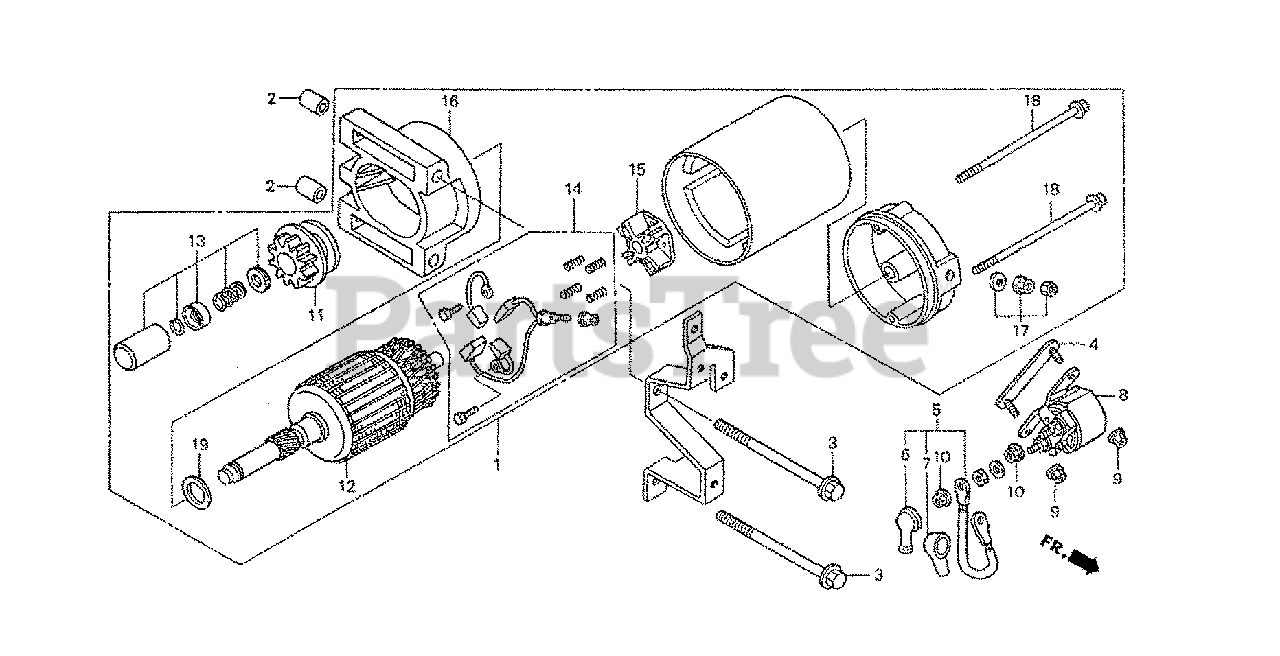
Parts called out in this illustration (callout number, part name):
1	MOTOR ASSY., STARTER
2	PIN, DOWEL (10X12)
3	BOLT, FLANGE (8X110)
11	GEAR SET, PINION
12	ARMATURE
13	STOPPER SET, PINION
14	BRUSH SET
15	HOLDER, BRUSH
16	BRACKET, FR.
17	NUT SET, TERMINAL
18	BOLT, THROUGH
19	WASHER, THRUST
